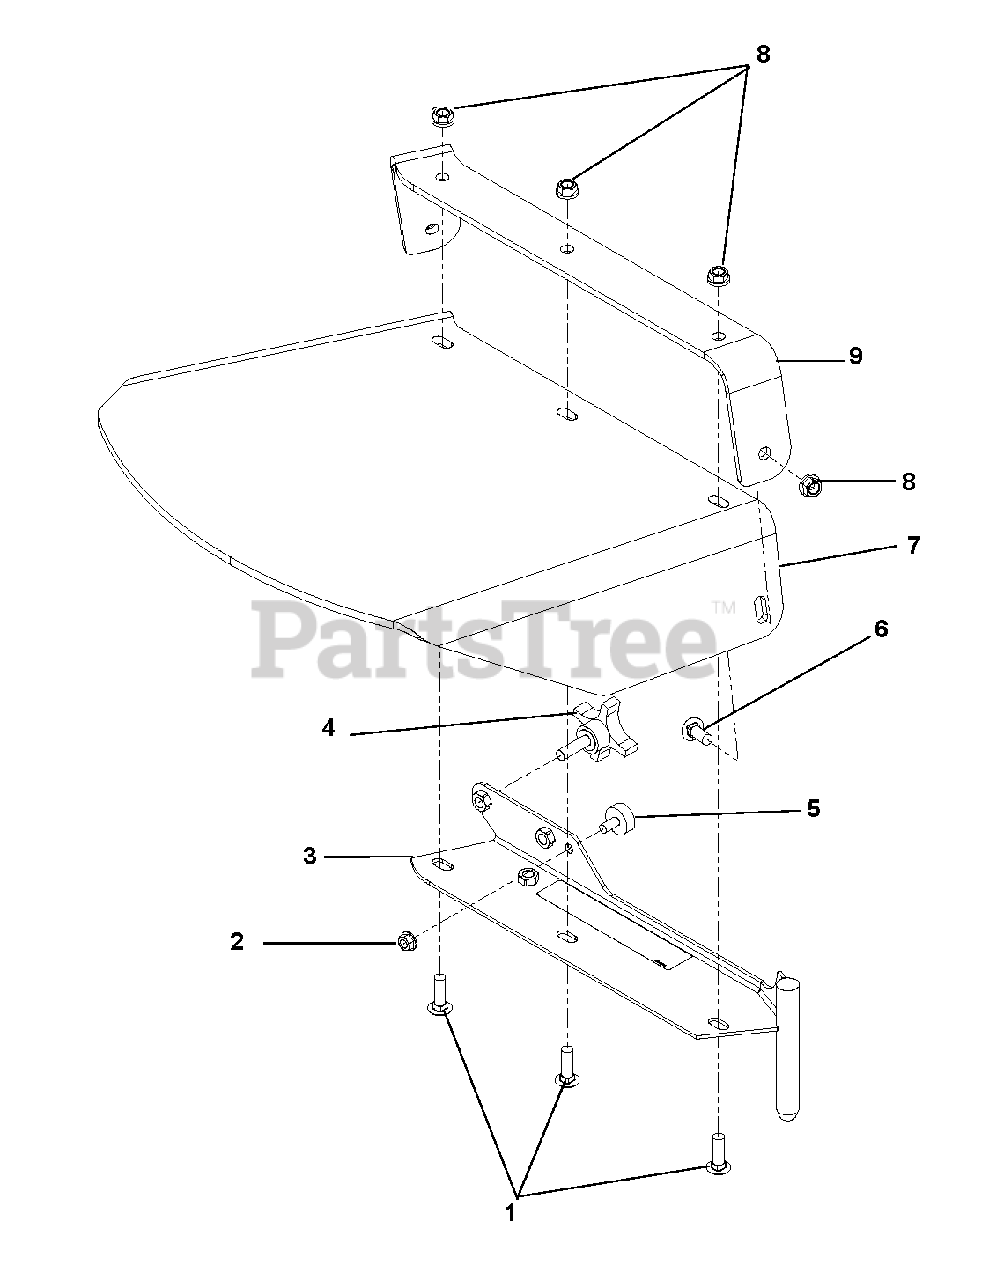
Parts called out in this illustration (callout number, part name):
1	Bolt, Round Head Square Neck .38-16 x 1.25 Grade 5
2	Locknut, .313-18 Whiz
3	Weldment, Discharge
4	Knob, .375 x 1.25-4 Prong
5	Bumper, Rubber
6	Bolt, Round Head Square Neck .38-16 x 1.00 Grade 5
7	Shield, Walk Rubber Discharge
8	Nut, Spin Lock Flange .375-16
9	Strap, EverRide Walk Rubber Discharge Chute
